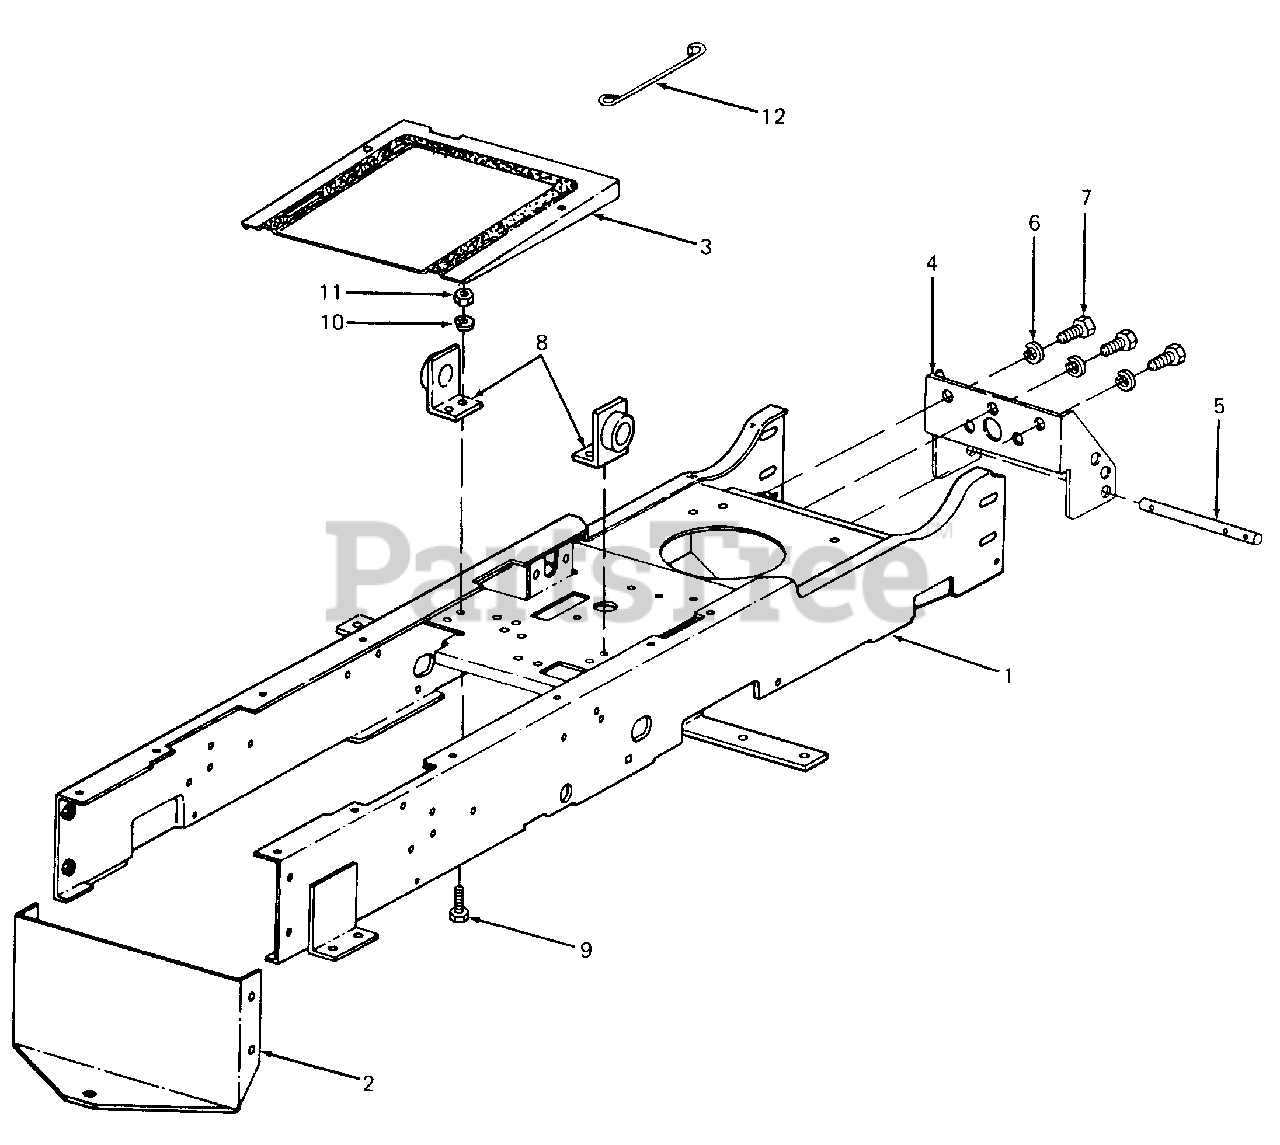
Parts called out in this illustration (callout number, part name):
3	Cover, Frame w/Graphic
6	Washer, Lock, 3/8
7	Screw, Hex Cap, 3/8-16
8	Bracket, Lift Shaft
9	Screw, Hex Cap, 5/16-18 X .75 Lg GR5
10	Washer, Lock, 5/16
11	Nut, Hex, 5/16-18
12	Rod, Link Retaining
